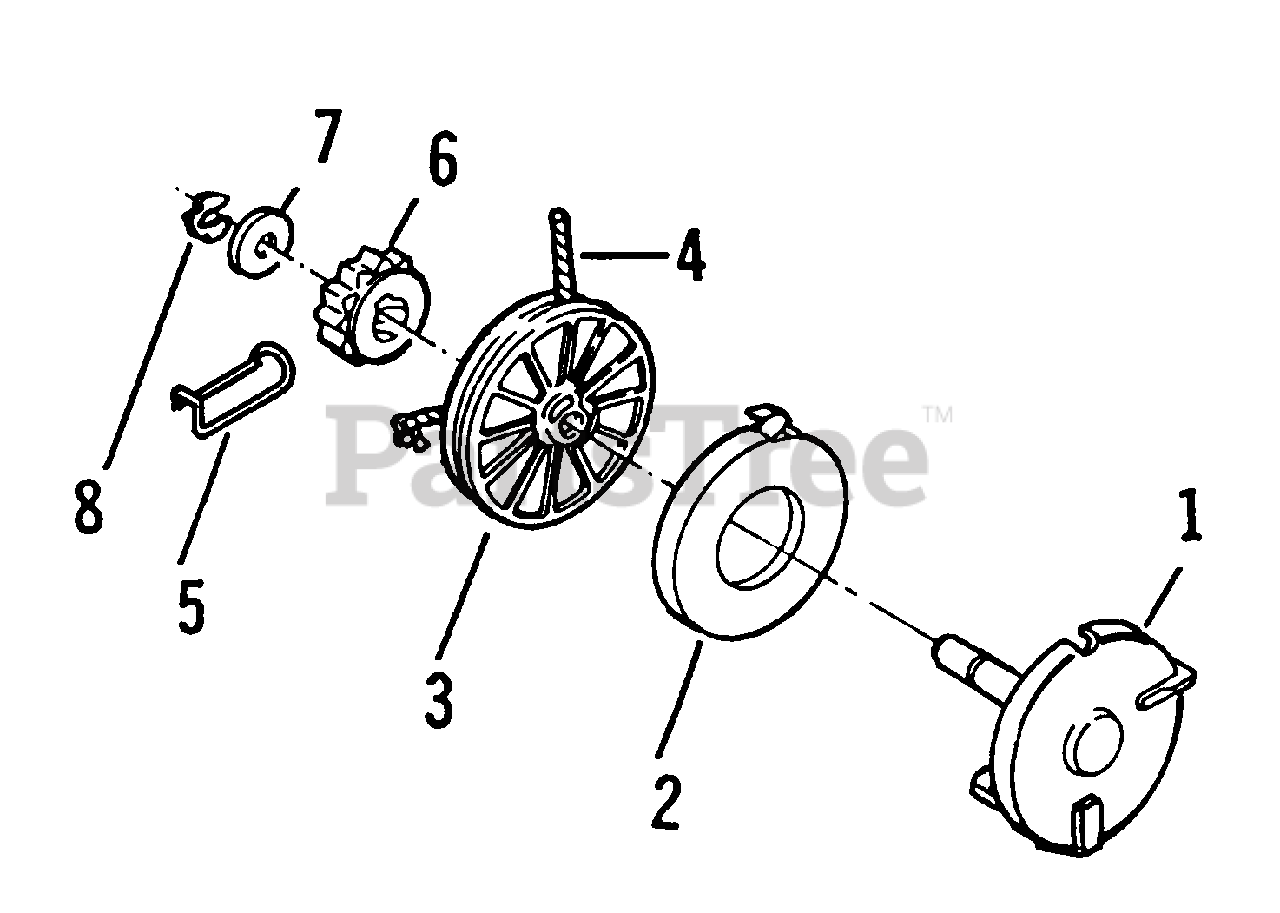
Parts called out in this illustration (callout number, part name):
1	Spring Cup and Pin Assembly
2	Spring and Retainer Assembly
3	Pulley
4	Rope
5	Spring-Drag
6	Pinion
7	Washer
8	Retainer
